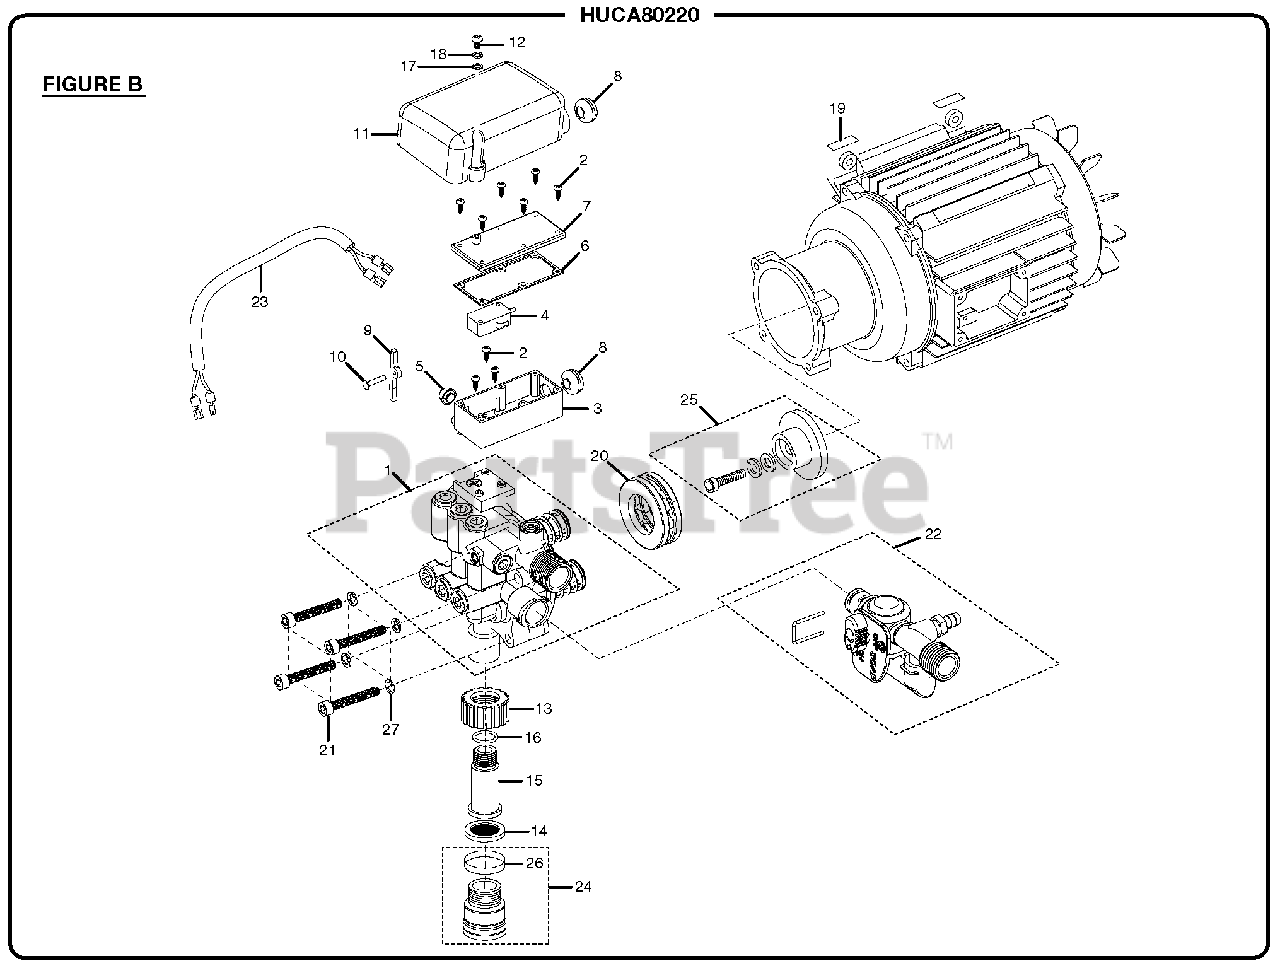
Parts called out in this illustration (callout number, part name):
1	Pump Assembly
2	Screw (M2.9 x 10 mm)
3	Switch Box
4	Stop Switch
5	Switch Box Seal
6	Switch Box Gasket
7	Switch Box Cover
9	Stop Switch Lever
10	Stop Switch Lever Pin
11	Stop Switch Protective Cover
12	Screw (M4 x 10 mm)
13	Hose Connector
14	Inlet Filter
15	Hose Adaptor
18	Lock Washer
19	Induction Motor Assembly
20	Bearing
21	Screws (M6 x 45 mm)
22	Soap Dispenser Assembly
23	Stop Switch Wiring Harness Assembly
24	Backflow Preventer (Inc. Key 26)
25	Wobble Plate w/Screw
26	Backflow Preventer Label
27	Lock Washer (M6)
